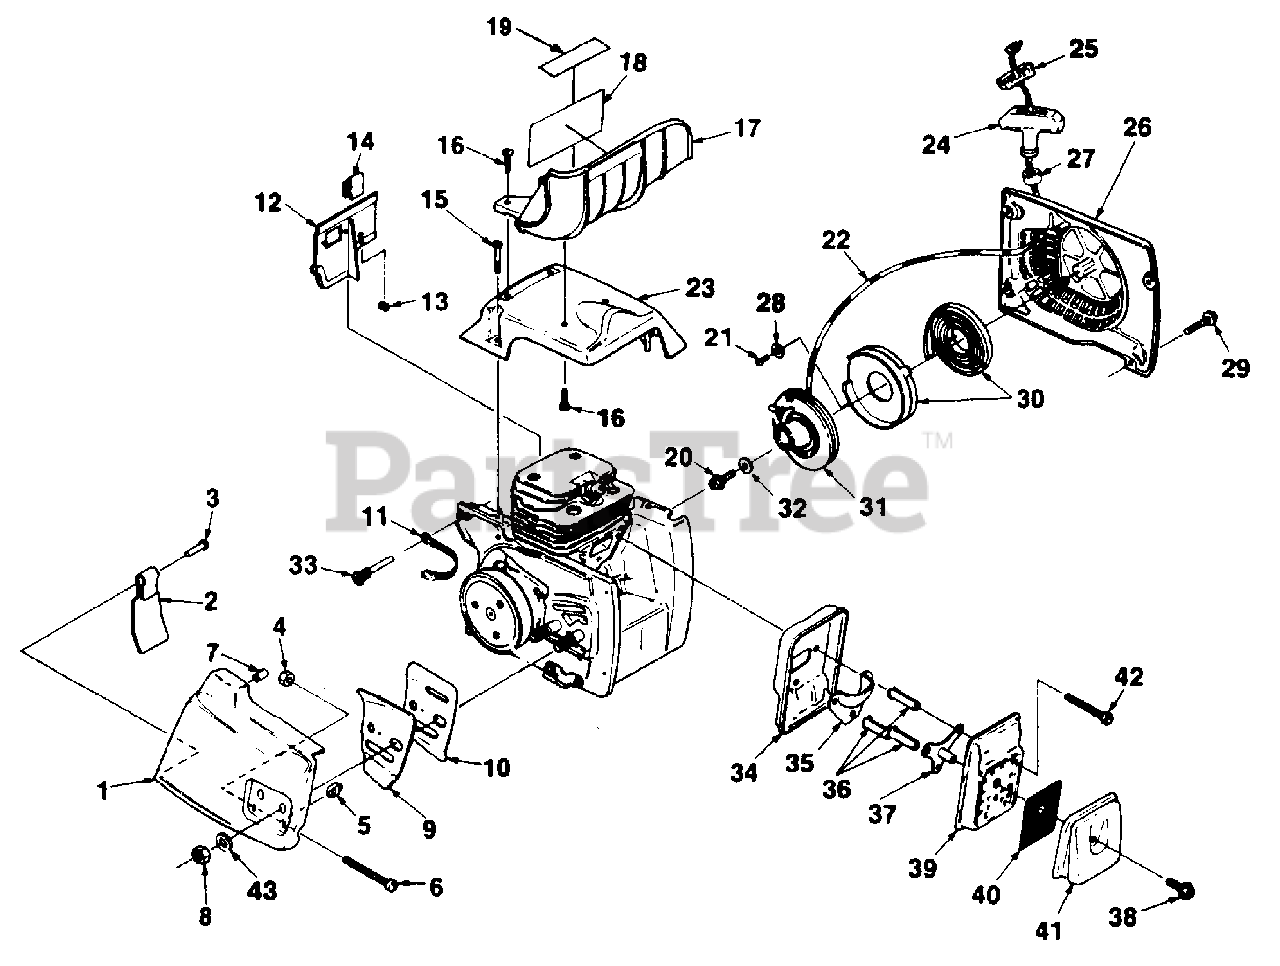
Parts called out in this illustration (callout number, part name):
1	COVER- Drivecase
2	SHIELD- Sawdust
3	RIVET- Pan hd.
4	NUT- Hex (1/4-20)
5	PIN- Guide bar adj.
6	SCREW- Guide bar adj.
7	BUSHING
8	NUT-(3/8-16)
9	PLATE- Guide bar (outer) 410 only
10	PLATE- Guide bar (inner)
11	STRAP- Ground
12	DEFLECTOR- Air
13	GROMMET
14	SPRING- Clip
15	SCREW- Cylinder cover (8-32 x 7/8")
16	SCREW- Threaded rolling plastite (#10 x 5/8")
17	GUARD- Hand
18	DECAL- Safety warning
19	LABEL- Ansi
20	SCREW- (#10 x 5/8")
21	SCREW- Plastite (6 x 3/8")
22	ROPE- Starter (#5) 45"
23	COVER- Cylinder (410 only)
24	GRIP- Starter rope
25	INSERT- Rope retaining
26	HOUSING- Starter
27	BUSHING
28	WASHER- Flat
29	SCREW- Hex Sems (10-24 x 5/8")
30	SPRING & RETAINER
31	STARTER PULLEY & CUP
32	WASHER- Retaining
33	PIN- Isolator
34	BODY- Muffler
35	PLATE- Stiffner
36	SPACER- Muffler
37	SPACER & PLATE
38	SCREW- Hex Sems (10-32 x 3/8")
39	COVER- Muffler
40	SCREEN- Spark
41	CAP- Muffler exhaust
42	SCREW- Hex hd. (12-24 x 17/8")
43	WASHER- Flat
